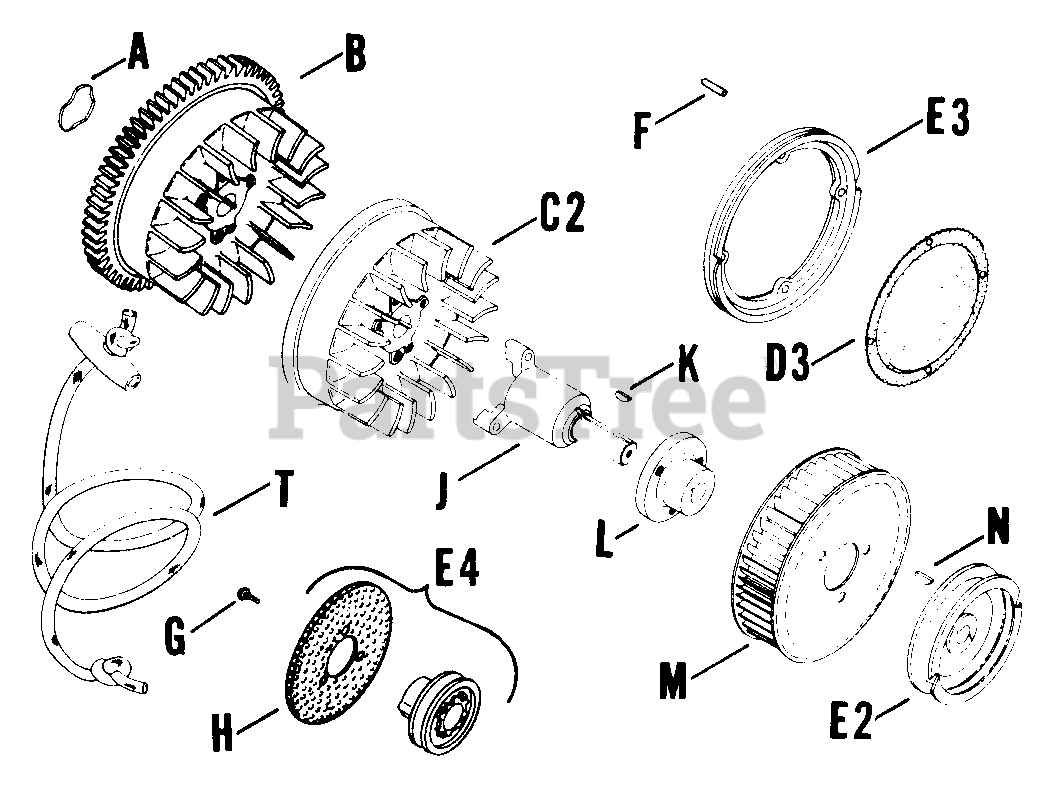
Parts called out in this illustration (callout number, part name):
A	WASHER - DISCONTINUED
N	KEY - DISCONTINUED
T	ROPE-DISCONTINUED
